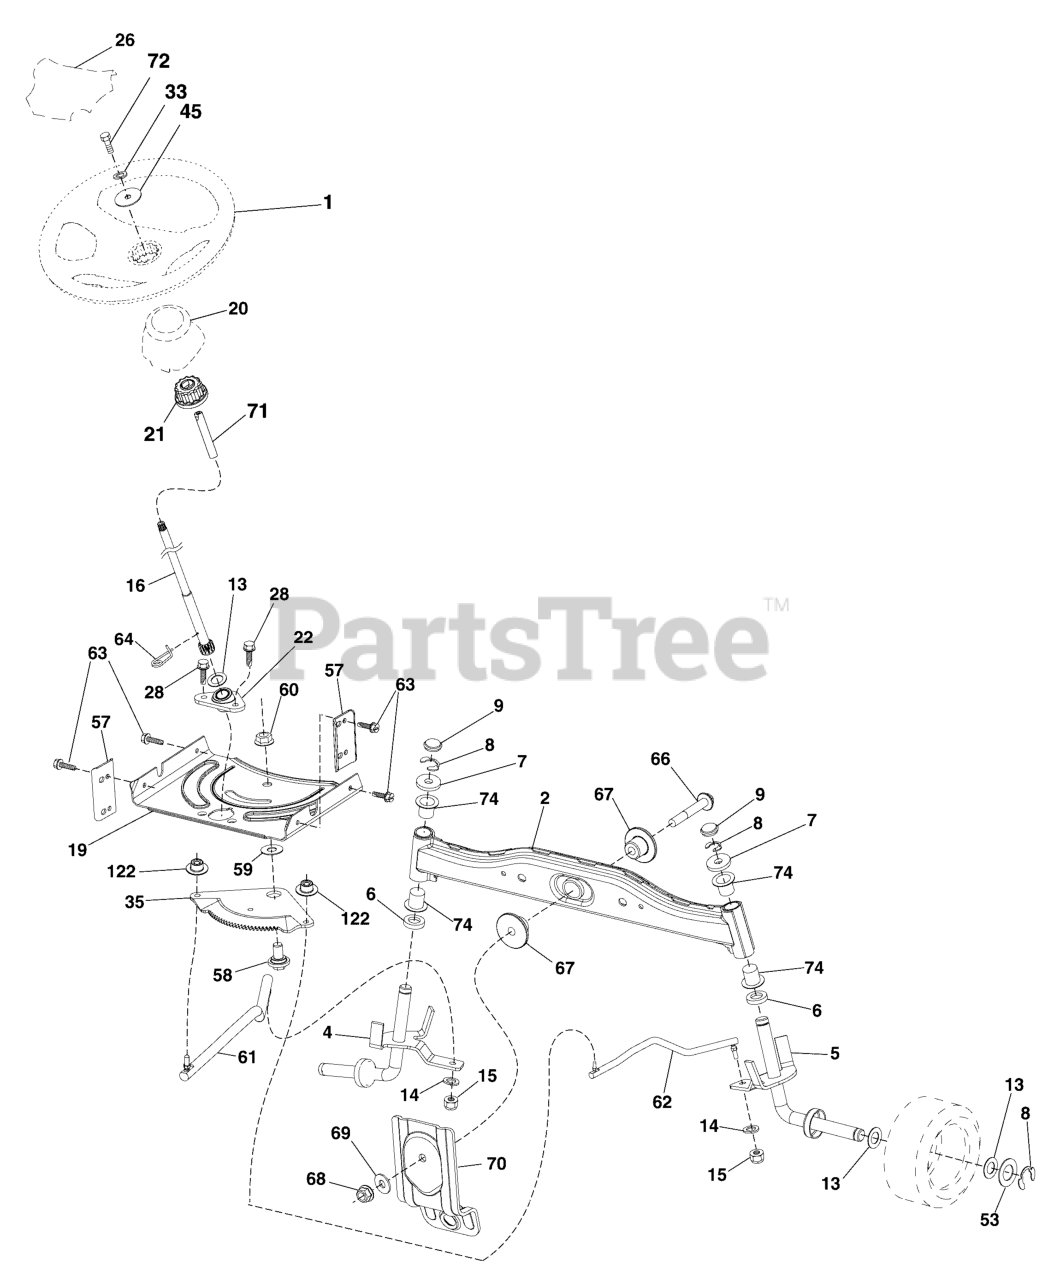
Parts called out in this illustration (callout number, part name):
1	WHEEL, Steering
2	AXLE, Assembly Front
4	SPINDLE, Assembly LH
5	SPINDLE, Assembly RH
6	WASHER, Thrust 0.75 x 1.23
7	WASHER, 25/32 x 1-5/8 x 16 Ga.
8	RING, Clip #T5304-75
9	CAP, Spindle
13	WASHER, 25/32 x 1-1/4 x 16 Ga.
14	WASHER, Lock, 3/8
15	NUT, Crown Lock, 3/8-24 UNF
16	SHAFT, Steering
19	PLATE, Steering
20	BOOT, Steering
21	ADAPTER, Wheel Steering
22	SUPPORT, Lower
26	INSERT, Wheel Steering
28	SCREW, 3/8-16 x 3/4
33	WASHER, Lock, 5/16
35	GEAR, Sector Plate
45	WASHER, 11/32 x 2-3/8 x 12 Ga.
53	WASHER, Hardened .793 x 1.637 x .060
57	BRACKET, Upstop
58	BOLT, Shoulder Sector Pivot CFM
59	WASHER, Thrust Sector Steering
60	NUT, Flange Lock, 5/8-11
61	DRAGLINK, LH
62	DRAGLINK, RH
63	SCREW, 5/16-18 x 3/4
64	RETAINER, Clip Spring Steering
66	BOLT, Hex Flange Head, 7/16-14 x 3
67	BUSHING, PM Front Axle
68	NUT, Lock Flange, 7/16-14 Gr 5
69	WASHER, 1.5 x .505 x .118
70	BRACKET, Deck Suspension Front
71	SHAFT, Steering
72	BOLT, w/Patch, 5/16-18 x 4
74	BEARING
122	CAP, Gear Sector Tex
